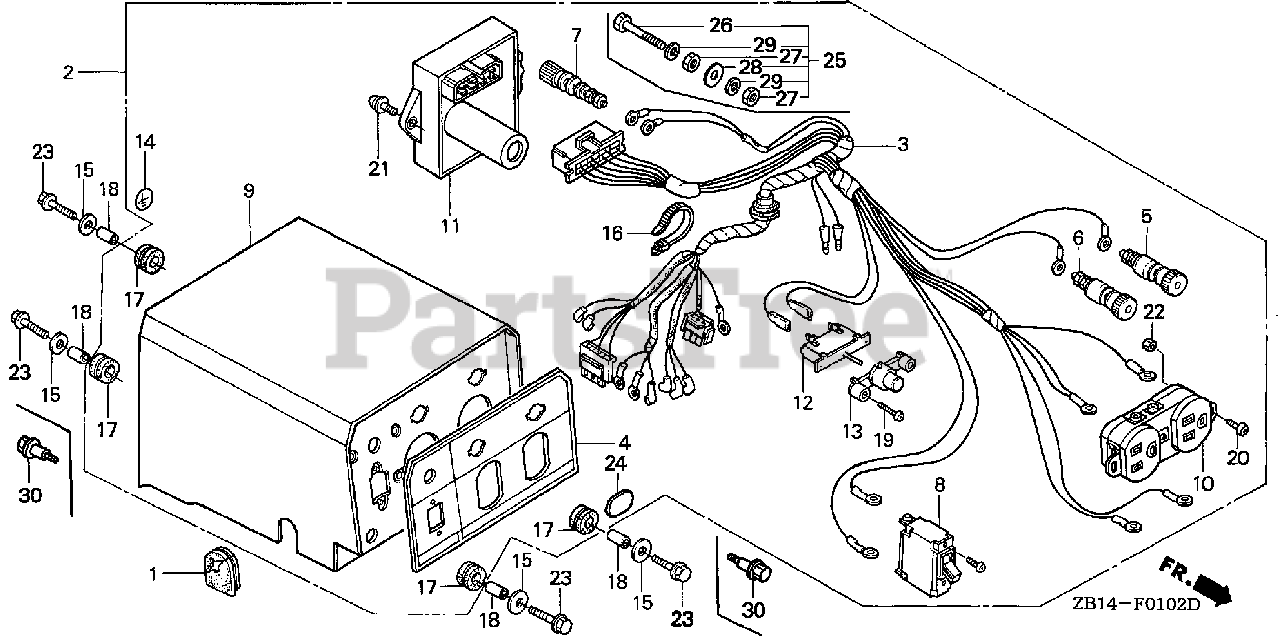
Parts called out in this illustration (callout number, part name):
1	GROMMET, WIRE
2	BOX ASSY., CONTROL *R280* (POWER RED)
3	WIRE HARNESS ASSY.
4	MARK, SWITCH PANEL
5	TERMINAL, D.C. OUTPUT (+)
6	TERMINAL, D.C. OUTPUT (-)
8	BREAKER, CIRCUIT (20A)
9	BOX, CONTROL *R280* (POWER RED)
10	RECEPTACLE (20A/125V) (MATSUSHITA)
11	REGULATOR UNIT, AUTOMATIC
12	PROTECTOR, CIRCUIT (D.C.)
13	LENS ASSY., PROTECTOR
14	MARK, GROUND
17	RUBBER, CONTROL BOX
19	SCREW, PAN (3X12)
20	SCREW, PAN (4X16)
21	SCREW-WASHER (5X12)
22	NUT, FLANGE (4MM)
24	PLATE, SEAL *R280* (POWER RED)
25	TERMINAL SET, GROUND
26	BOLT, HEX. (6X28)
27	NUT, HEX. (6MM)
28	WASHER, PLAIN (6MM)
29	WASHER, SPRING (6MM)
30	BOLT, ADJUSTING (6X20)
